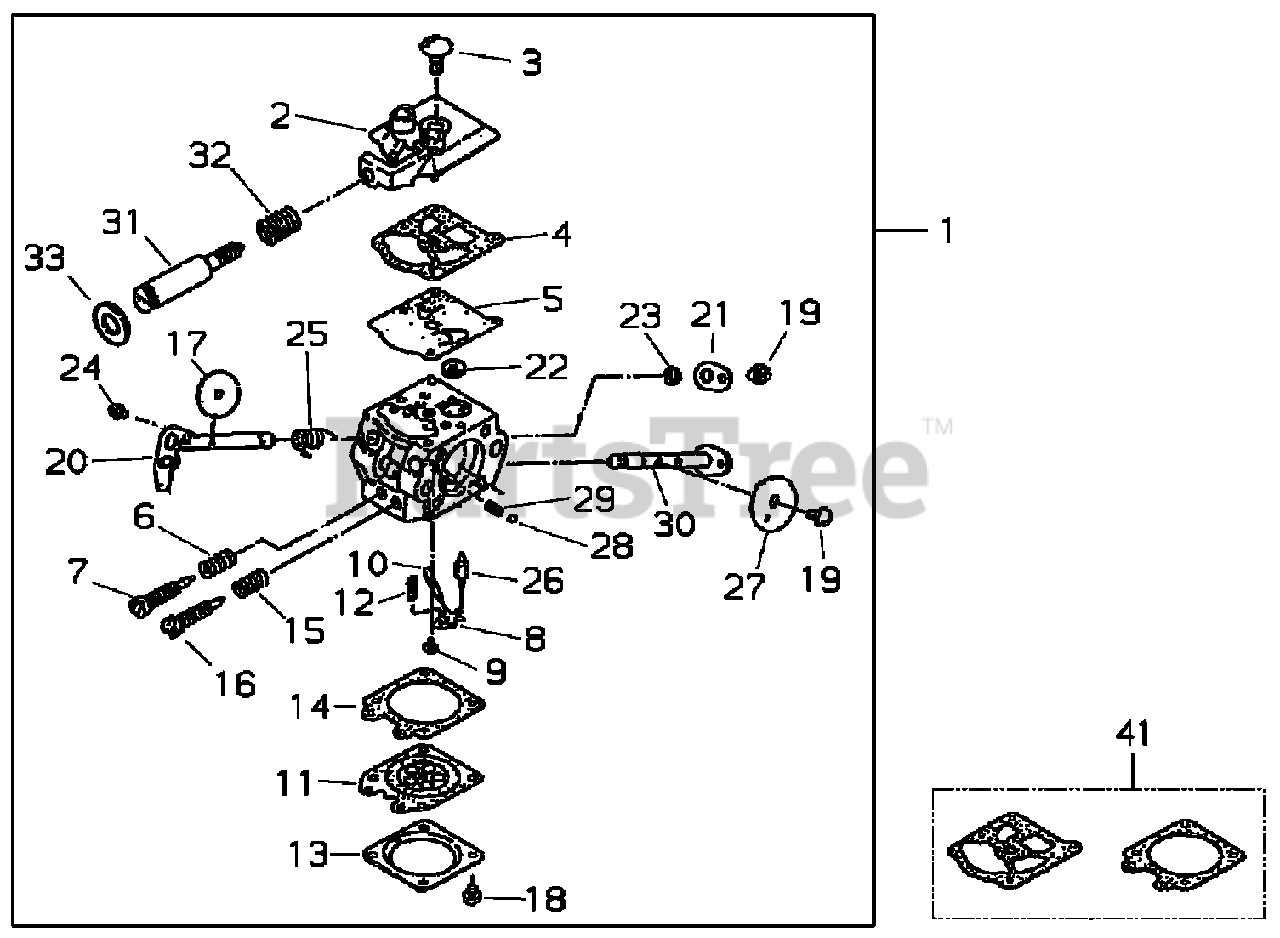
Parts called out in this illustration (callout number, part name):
1	CARBURETOR
2	COVER ASSY, PUMP
3	SCREW
4	GASKET, FUEL PUMP
5	DIAPHRAGM, PUMP
6	SPRING, NEEDLE
7	NEEDLE, LOW SPEED
8	LEVER, METERING
9	SCREW, METERING LEVER PIN
10	PIN, METERING LEVER
11	DIAPHRAGM, METERING
12	SPRING, METERING LEVER
13	COVER, METERING DIAPHRAGM
14	GASKET, METERING DIAPHRAGM
15	SPRING, HIGH NEEDLE
16	NEEDLE, HIGH SPEED
17	VALVE, THROTTLE
18	SCREW
19	SCREW
20	SHAFT, THROTTLE
21	LEVER, THROTTLE
22	SCREEN, FUEL INLET
23	E-RING
24	SCREW ASSY
25	SPRING, THROTTLE RETURN
26	VALVE, INLET NEEDLE
27	VALVE, CHOKE
28	BALL, CHOKE FRICTION
29	SPRING
30	SHAFT, CHOKE
31	SCREW, IDLE ADJUST
32	SPRING, IDLE ADJUST
33	SEAL, COLLAR
41	GASKET KIT
